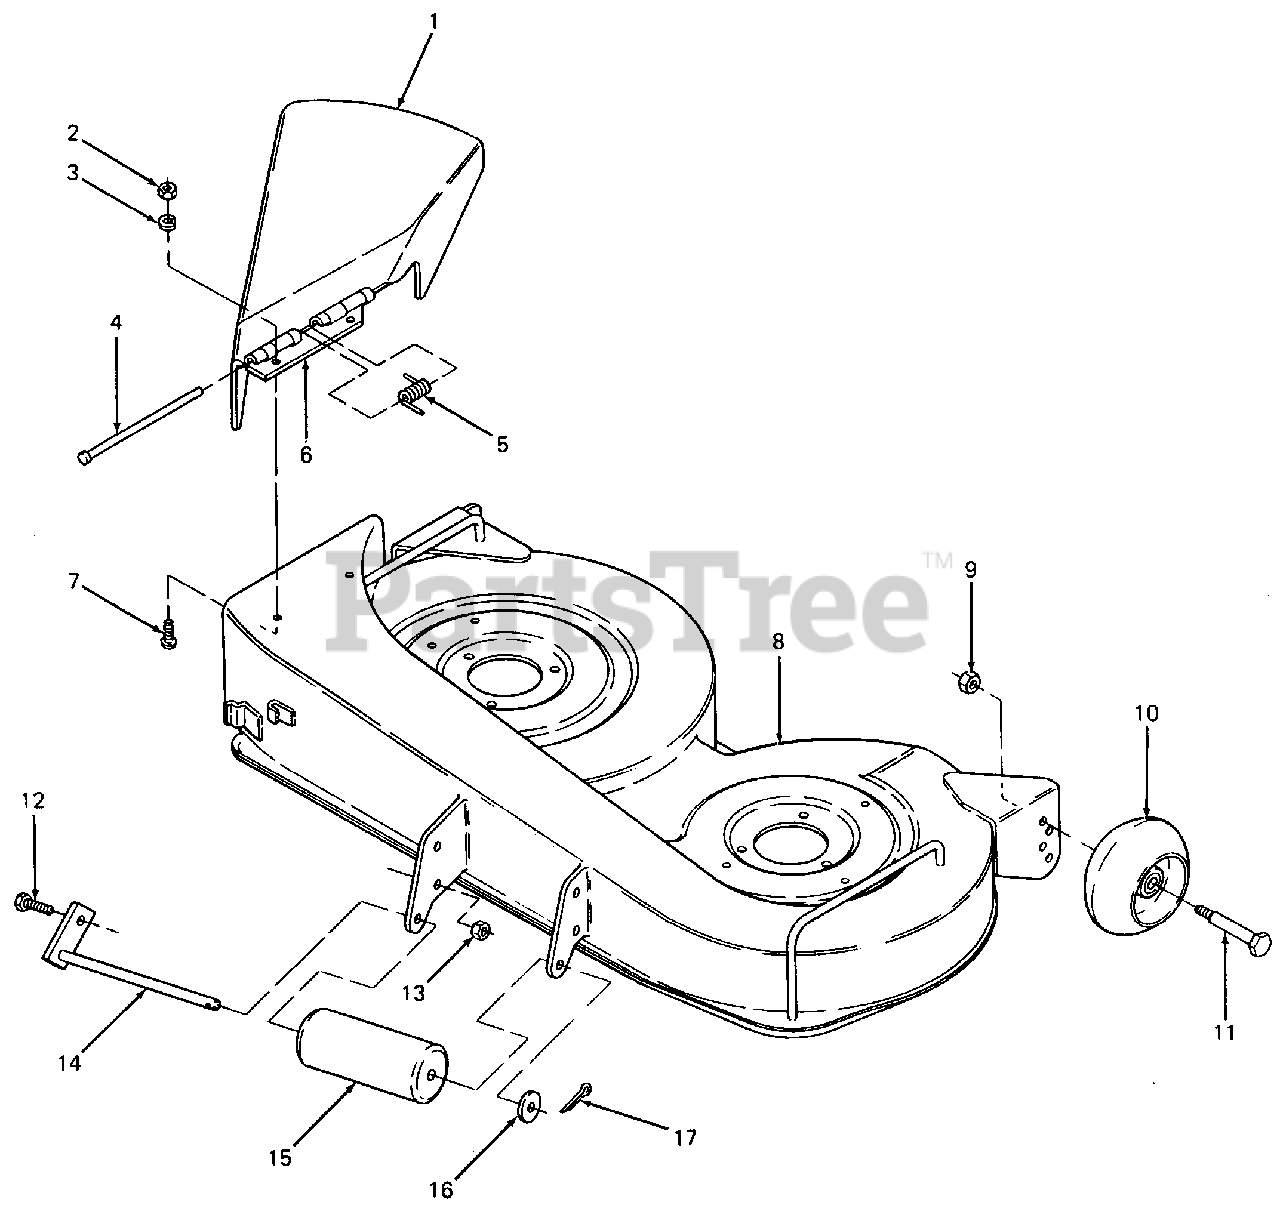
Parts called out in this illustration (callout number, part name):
1	Chute, Discharge w/Graphic
2	Nut, Hex Jam, 1/4-20
3	Washer, Lock, 1/4
4	Pin, Hinge, .25 Dia X 6.75 Lg
5	Spring, Torsion, .29 ID x 1.14 Lg
6	Hinge, Discharge Chute
7	Screw, Truss Mach, 1/4-20 X .75 Lg
8	Deck Assy w/Graphics
9	Nut, Hex Center Lock, 3/8-16
10	Wheel, Ball, 5" Dia
11	Screw, Shoulder
12	Screw, Hex Cap, 1/2-13 X 1.0 Lg GR5
13	Nut, Hex Center Lock, 1/2-13
14	Pin, Roller
15	Roller, Front
16	Washer, Flat, .531 X 1.25 X .100 Thk
17	Pin, Cotter, 1/8 Dia X 1.25 Lg
